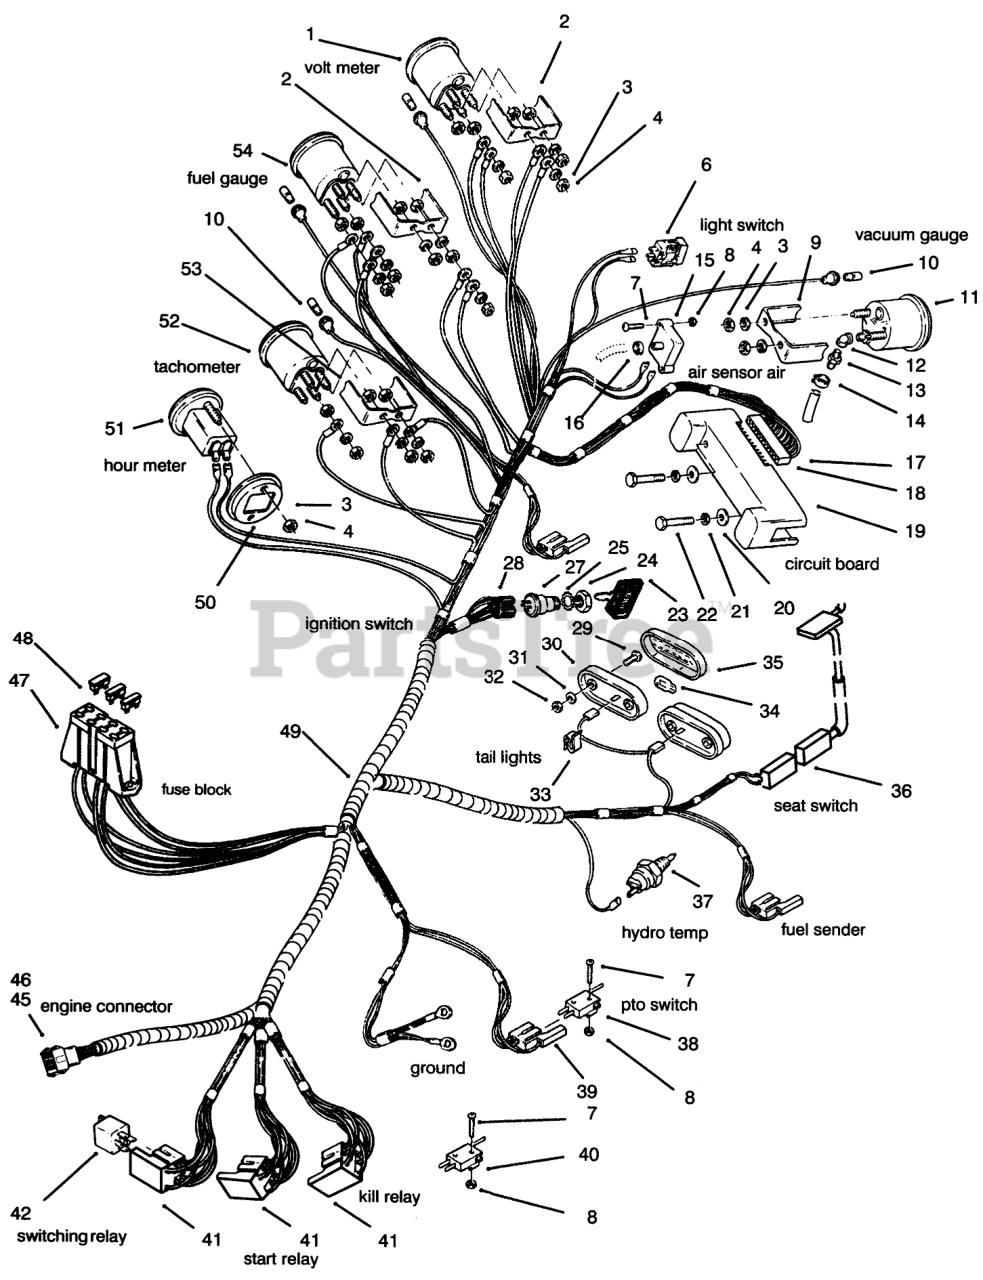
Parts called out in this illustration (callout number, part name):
1	Voltmeter (Incl. Ref. #2-4)
2	CLAMP-MOUNTING
3	WASHER-LOCK
4	NUT-HEX
6	SWITCH-HEADLIGHT
7	Screw
8	NUT-HEX
9	Bracket-Mounting
10	LAMP-MINIATURE GE 53X
11	Gauge-Vacuum (Incl. Ref. #3-4 & 9)
12	ELBOW
13	FITTING STRAIGHT
14	Clamp
15	SENSOR-AIR CLEANER
16	CLAMP-HOSE 5/16"
17	Terminal
18	Connector-Male
19	CIRCUIT-BRD 8 LIGHT
20	WASHER-FLAT
21	WASHER-LOCK
22	Screw
23	KEY-IGNITION
25	WASHER-LOCK
27	Switch-Ignition (Incl. Ref. #24-25)
28	CONNECTOR-5 WAY-SERV
29	SCREW-PPH
30	BASE-TAIL LIGHT
31	WASHER-LOCK, INT
32	NUT-LOCK, NI
33	SPEED CLIP
34	LIGHT BULB
35	LENS-TAIL LIGHT
36	SWITCH-SEAT
37	SENSOR-HYDRO OIL HOT
38	SWITCH
39	CONNECTOR BODY
40	SWITCH - CLUTCH
41	Connector-Relay
42	RELAY
47	FUSE-HOLDER 4 WAY
48	FUSE-10 AMP
49	WIRING-HARNESS & DIA
50	CLAMP-HOUR METER
51	Hourmeter (Incl. Ref. #3-4 & 49)
52	Tachometer (Incl. Ref. #1, 3-4 & 52)
53	BRACKET - GAUGE MOUNT
54	Gauge-Fuel (Incl. Ref. #2-4)
